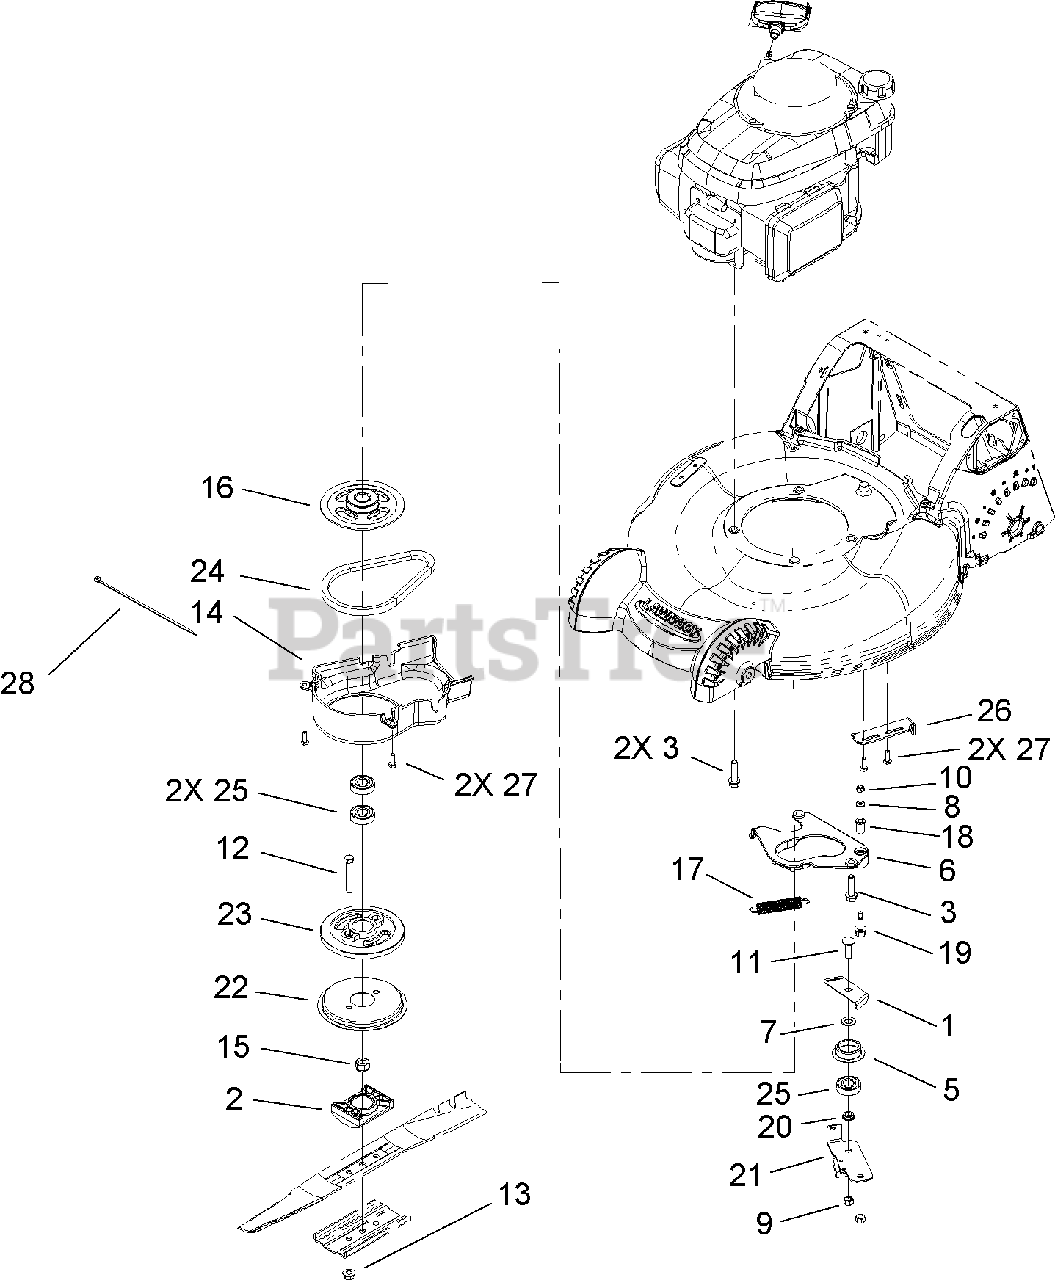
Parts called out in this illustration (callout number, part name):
1	PLATE-GUIDE
2	SUPPORT-BLADE
3	SCREW-HWH
5	RETAINER-BELT
6	PLATE-ANCHOR
8	WASHER-FLAT
10	NUT-LOCK, NI
11	SCREW-CARR
12	SCREW-HH
13	NUT-LOCK
17	SPRING-TENSION, BRAKE
19	BOLT-SHOULDER
20	SPACER-BEARING
21	BRAKE ARM ASM
22	DISC
23	DRUM
25	BEARING-BALL
26	BRACKET-CABLE
27	SCREW-HWHTF
28	STRAP-TIE
